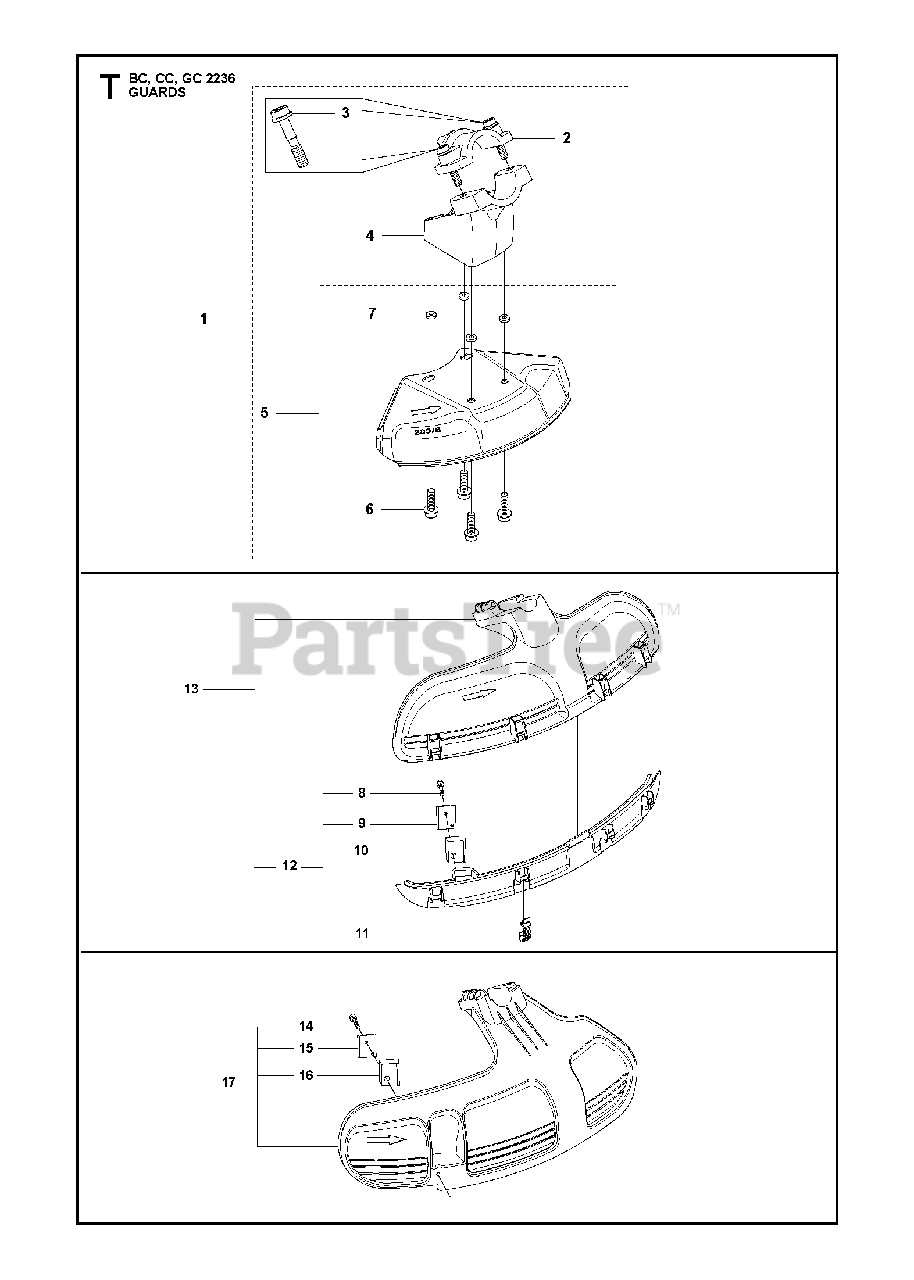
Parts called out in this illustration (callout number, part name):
1	ADAPTER
2	CLAMP
3	SCREW IHSCFMO
4	ADAPTER
5	BLADE GUARD
6	SCREW
7	LOCKING NUT
8	SCREW
9	LINE CUTTER
10	DISTANSBLOCK
11	BUCKLE
12	SPLASH GUARD
13	SPLASH GUARD
13	COMBI PROTECTOR
14	SCREW
15	LINE CUTTER
16	DISTANSBLOCK
17	TRIMMER GUARD
